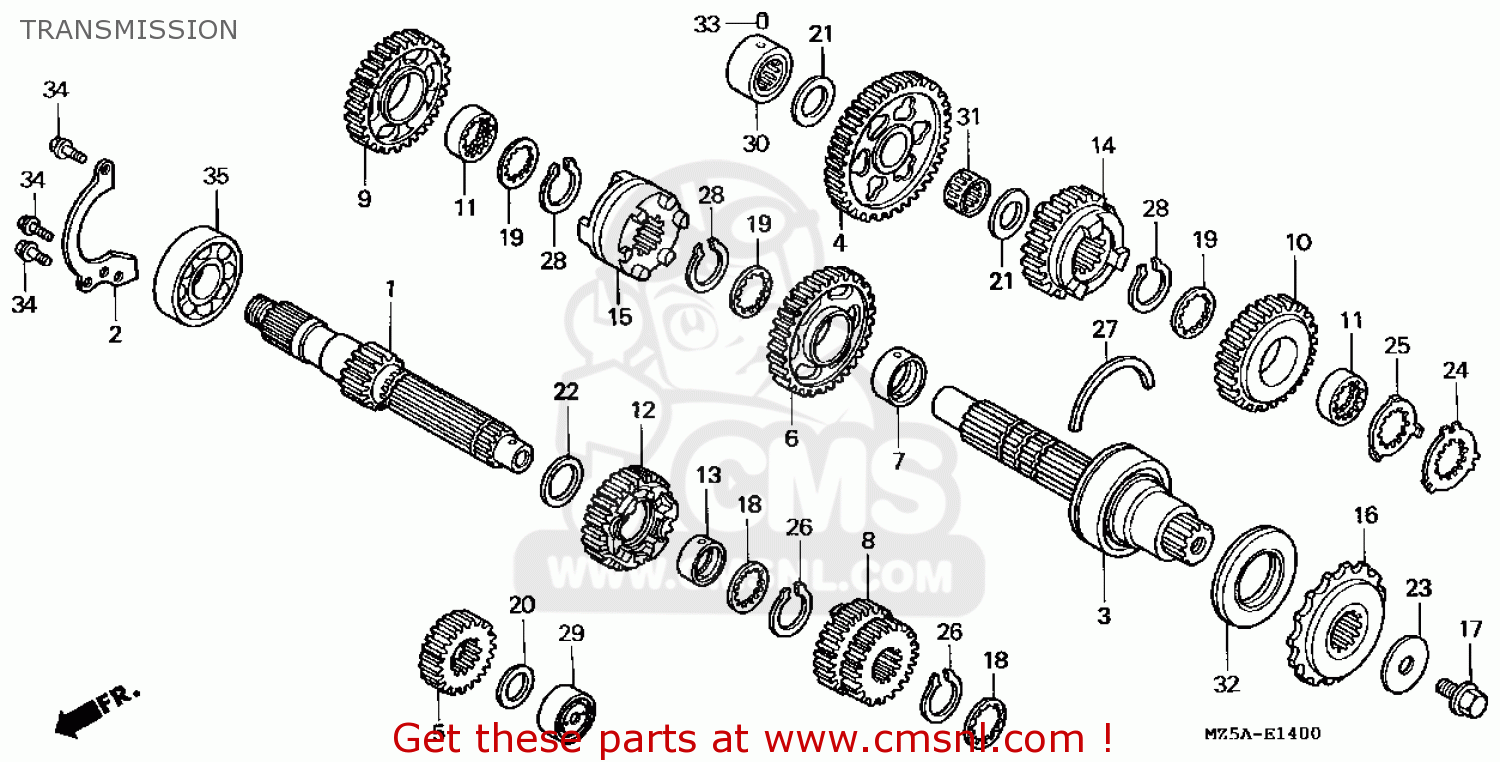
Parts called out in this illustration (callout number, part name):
1	SHAFT,MAIN
2	PLATE,BRG.SET
3	SHAFT COMP,COUNTE
4	GEAR,COUNTERSHAFT
5	GEAR,M-2
6	GEAR,C-2
7	COLLAR 28MM
8	GEAR,M-3,M-4
9	GEAR,C-3
10	GEAR,C-4
11	COLLAR,SPLINE 28X
12	GEAR,MAINSHAFT FI
13	COLLAR, 25X12
14	GEAR,C-5
15	SHIFTER,C6
16	SPROCKET,DRIVE (1
17	BOLT,SPECIAL,10MM
18	WASHER,SPLINE,25X
19	WASHER SPLINE 28X
20	WASH THRUST 20MM
21	WASHER,THRUST,22M
22	WASHER,25MM
23	WASHER,10.2MM
24	WASHER,SPLINE 28M
25	WASHER LOCK,28MM
26	CIR CLIP,25MM
27	RING,SET,68MM
28	CIRCLIP,28MM
29	BRG,NDL.20X34X17.
30	BRG,NDL 22MM
31	BRG,NDL.22X26X11
32	OIL SEAL 40X68X7.
33	PIN,KNOCK 8X10A
34	BOLT,FLANG,6X16
35	B/BRG RAD N/COM
